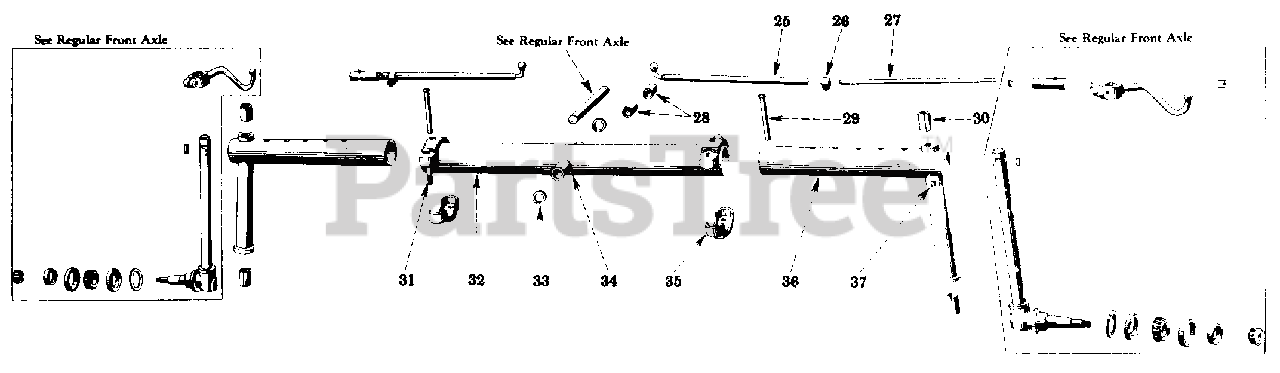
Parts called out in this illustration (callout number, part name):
25	TUBE ASSY, TIE ROD
26	TUBE ASSY, TIE ROD
26	CLAMP, TIE ROD
28	BUSHING, FRONT AXLE PIVOT
29	PIN, FRONT AXLE CLAMP
30	BUSHING, STEERING KNUCKLE POST
31	SCREW, 1/2-20 X 3 HEX-HD CAP FRONT AXLE CLAMP
32	AXLE
33	WASHER, FRONT AXLE PIVOT THRUST
34	FITTING, 1/4-28 NS TAPER STR LUB
35	CLAMP, FRONT AXLE
36	EXTENSION, FRONT AXLE
37	FITTING, 1/4-28 NS TAPER STR LUB
